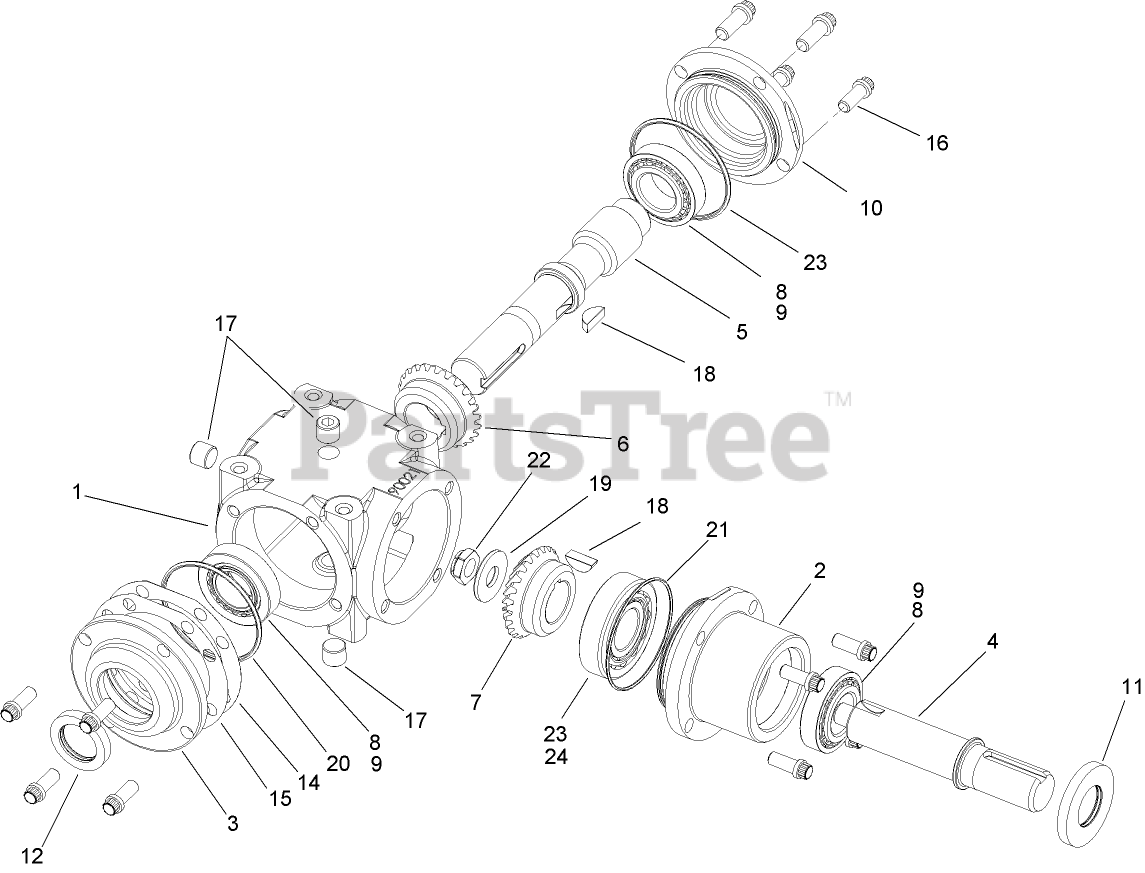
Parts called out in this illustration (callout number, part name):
2	HOUSING-PINION
3	CAP, END, OPEN
4	SHAFT-PINION
5	SHAFT, CROSS
6	GEAR-SHAFT, CROSS
7	GEAR-PINION
8	BEARING-CUP
9	BEARING-CONE
10	CAP-END, CLOSED
12	SEAL-SHAFT, CROSS
14	SHIM-BLUE, .005IN
15	SHIM-GREEN, .003IN
18	KEY-WOODRUFF
19	WASHER
20	O-RING
21	O-RING
22	NUT LOCK
23	BEARING-CUP
24	BEARING-CONE
